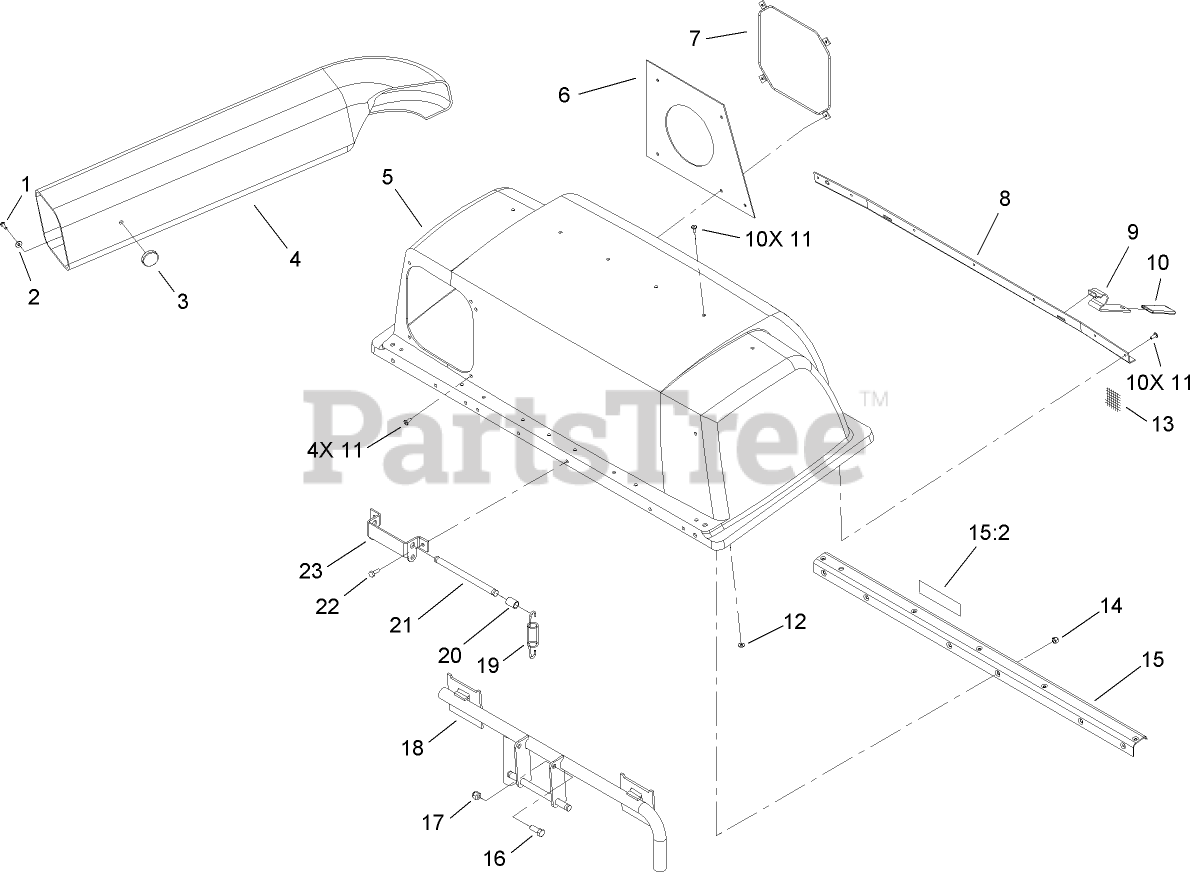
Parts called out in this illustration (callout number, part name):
1	SCREW-PPHTF
2	WASHER-PLAIN
4	CHUTE-DISCHARGE
5	TOP-BAGGER
6	SEAL-CHUTE
7	CLAMP-SEAL
8	SUPPORT-SCREEN
9	LATCH-BAGGER, TOP
11	RIVET-BLIND
12	WASHER-FLAT
13	SCREEN-BAGGER
14	NUT-LOCK, NI
15	STIFFENER ASM
15:2	DECAL-CAUTION
16	SCREW-HH
17	NUT-LOCK, NI
18	FRAME ASM
19	SPRING-EXTENSION
20	SPACER
21	PIN-SPRING
22	SCREW-HH
23	HINGE-BAG, TOP
